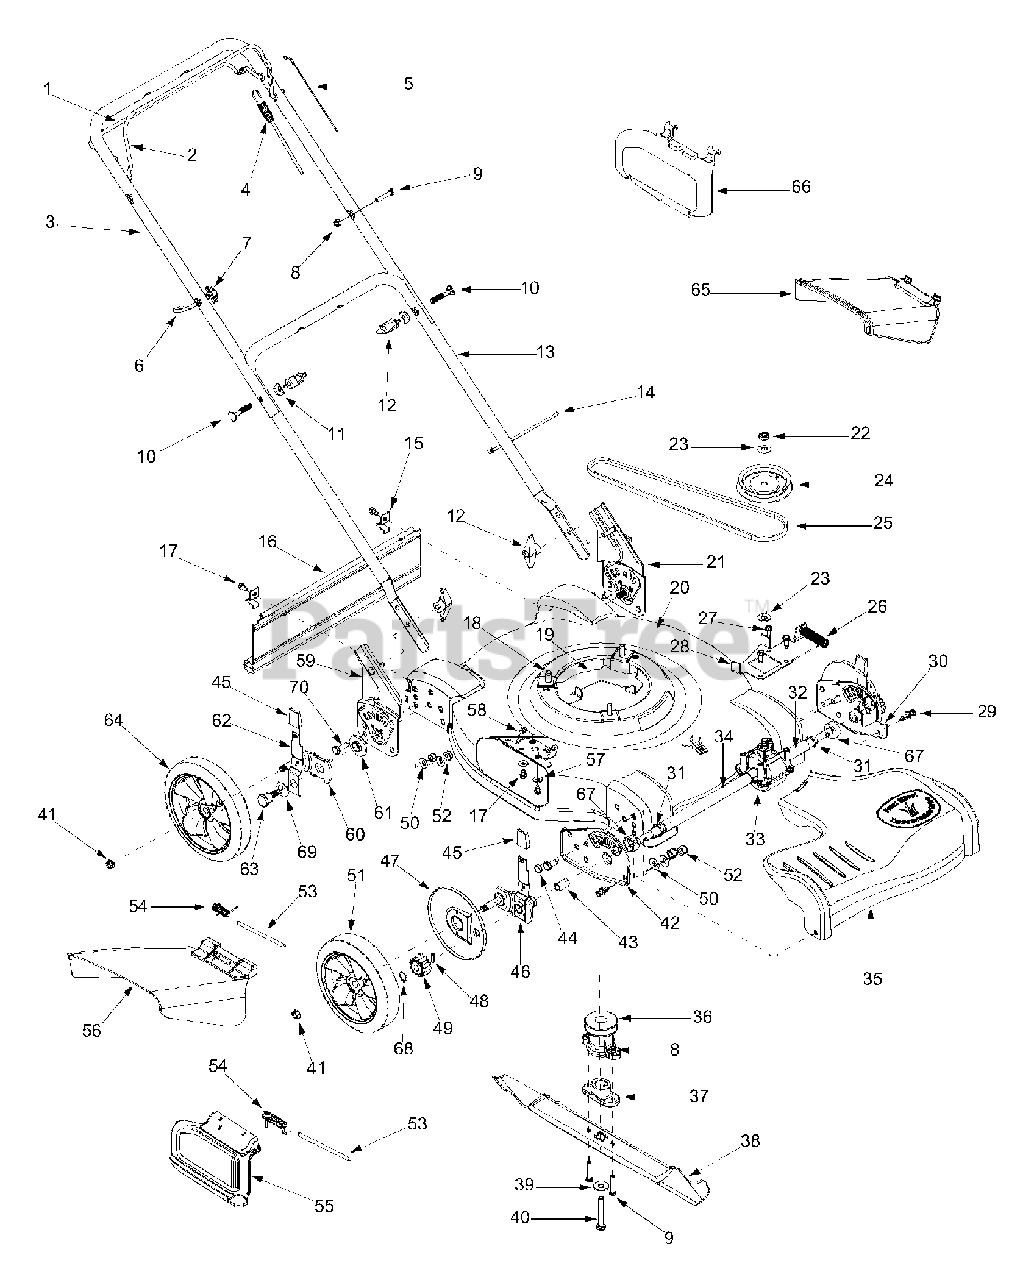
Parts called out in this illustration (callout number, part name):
1	Drive Control Handle
2	Blade Control Handle
4	Drive Control Cable 55.50"
4	Drive Control Cable 54"
5	Blade Control Cable - B&S (37.75")
5	Blade Control Cable - B&S (40.75")
5	Blade Control Cable- Tec (50")
6	Eye Bolt
7	Wing Nut 1/4-20
8	Hex Lock Nut 1/4-20
9	Hex Cap Screw 1/4-20x 1.5
10	Carriage Bolt 5/16-18 x 2.0
11	Shoulder Washer .320 ID x .93OD
12	Wing Nut 5/16-18
14	Cable Tie
15	Hinge Clip
16	Trail Shield
17	Hex Screw 1/4-14 x .625
18	Hex Washer Screw 3/8-16 x 1.0
19	Engine Belt Keeper Bracket
21	Handle Bracket Assembly - LH
22	Jam Nut 7/16-20
23	Bell Washer .45 ID x 1.00 OD
24	Pulley
26	Compression Spring
27	Hex Washer Screw 1/4-20 x .500
28	Transmission Belt Keeper Bracket
29	Rivet
30	Forward Height Adjustment Plate - LH
31	Retainer Ring
32	Sleeve Spacer .550 ID x 2.5
33	Transmission Assembly
34	Sleeve Spacer .550 ID x 8.9
35	Transmission Cover
36	Drive Pulley
37	Blade Adapter
38	Blade 22"
38	Mulching Blade 22"
39	Bell Washer .396 ID x 1.140 OD
40	Hex Cap Screw 3/8-24 x 1.5
41	Lock Nut 3/8-16
42	Forward Height Adjustment Plate - RH
43	Sleeve Bearing
44	Hex Cap Screw 3/8-16 x .75
45	Adjustment Knob
46	Spring Lever Assembly - LH* (FWD)
46	Spring Lever Assembly - RH* (FWD)
47	Wheel Dust Cover
49	Spur Gear 14T - LH
49	Spur Gear 14T - RH
50	Washer Spacer .401 ID x .870 OD
51	Front Wheel Assembly 8 x 1.8
52	Hex Lock Nut 3/8-16
53	Hinge Pin
54	Torsion Spring
55	Mulching Baffle (If Equipped)
56	Side Discharge Assembly
57	Bell Washer .265 ID x .75 OD
58	Chute Hinge
59	Handle Bracket Assembly - RH
60	Pivot Arm Assembly
61	Height Adjustment Bearing
62	Spring Lever
63	Shoulder Screw 3/8-16
64	Rear Wheel 8 x 1.8
65	Snap Discharge Chute (If Equipped)
66	Snap Mulching Plug (If Equipped)
67	Bearing Spacer
68	Snap Ring .500
69	Bell Washer .760 ID x 1.25 OD
70	Hex Cap Screw 3/8-16 x 1.0
